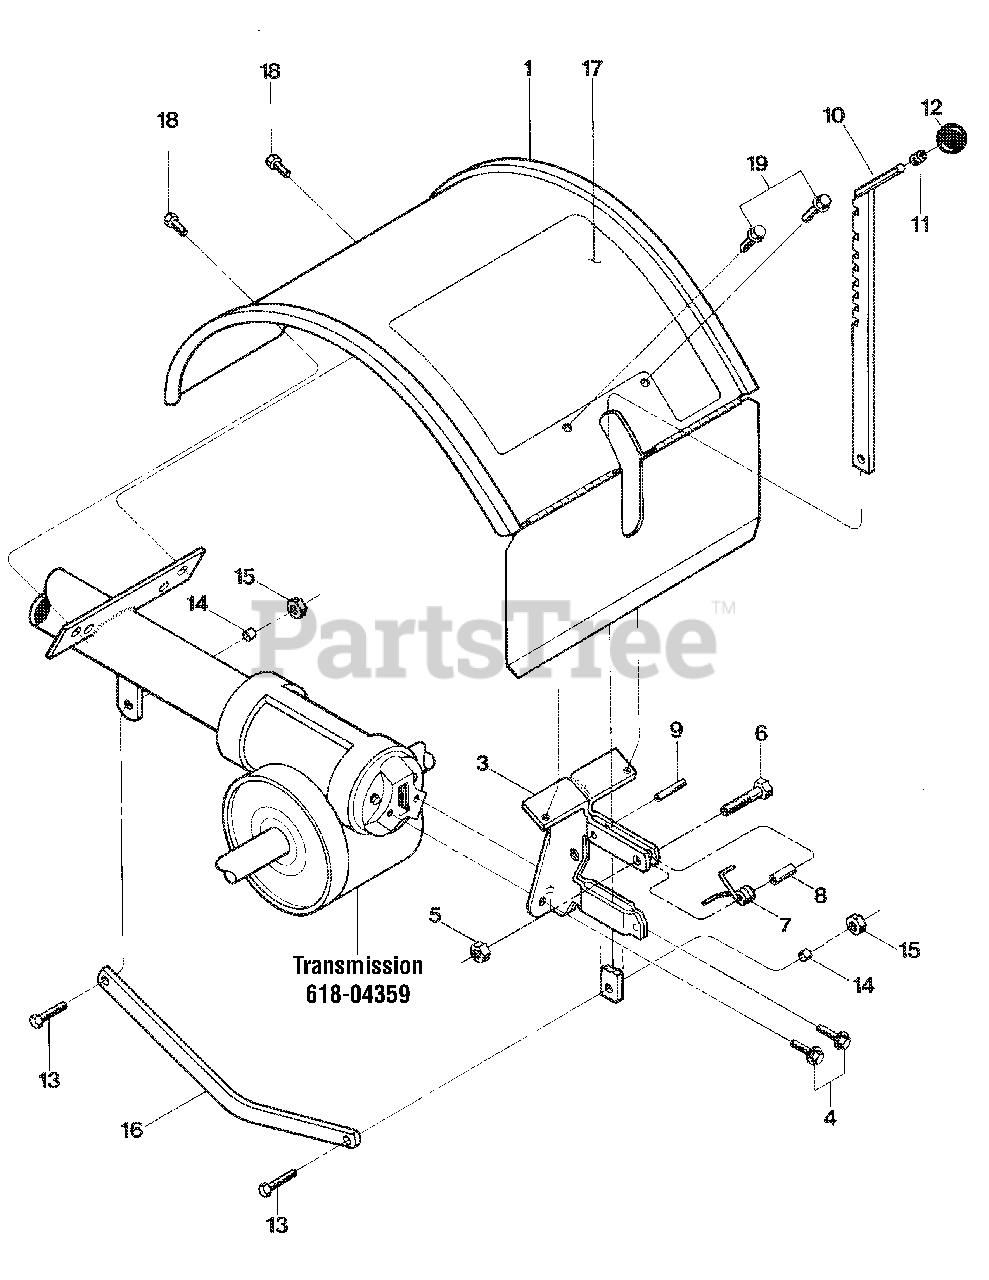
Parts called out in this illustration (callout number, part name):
3	Bracket - hood & depth regulator
4	Hex Flange Screw, 5/16-18 x 5/8
5	Hex Locknut, 1/4-20
6	Hex Hd. Screw, 1/4-20 x 1
9	Roll Pin (spiral), 1/4 x 1
10	Depth Adjustment Bar Assembly (Incl. Refs. 11 & 12)
11	Retaining Ring (tolerance ring)
12	Knob, Depth Regulator
13	Hex Hd. Screw, 3/8-16 x 1-1/4
14	Bushing, Drag Bar
15	Hex Nut, 3/8-16
16	Drag Bar
17	Decal, operating instructions
18	Hex Hd. Screw, self-tapping, 5/16-18 x 5/8"
19	Hex Flange Screw, self-tapping,1/4-20 x 1/2"
